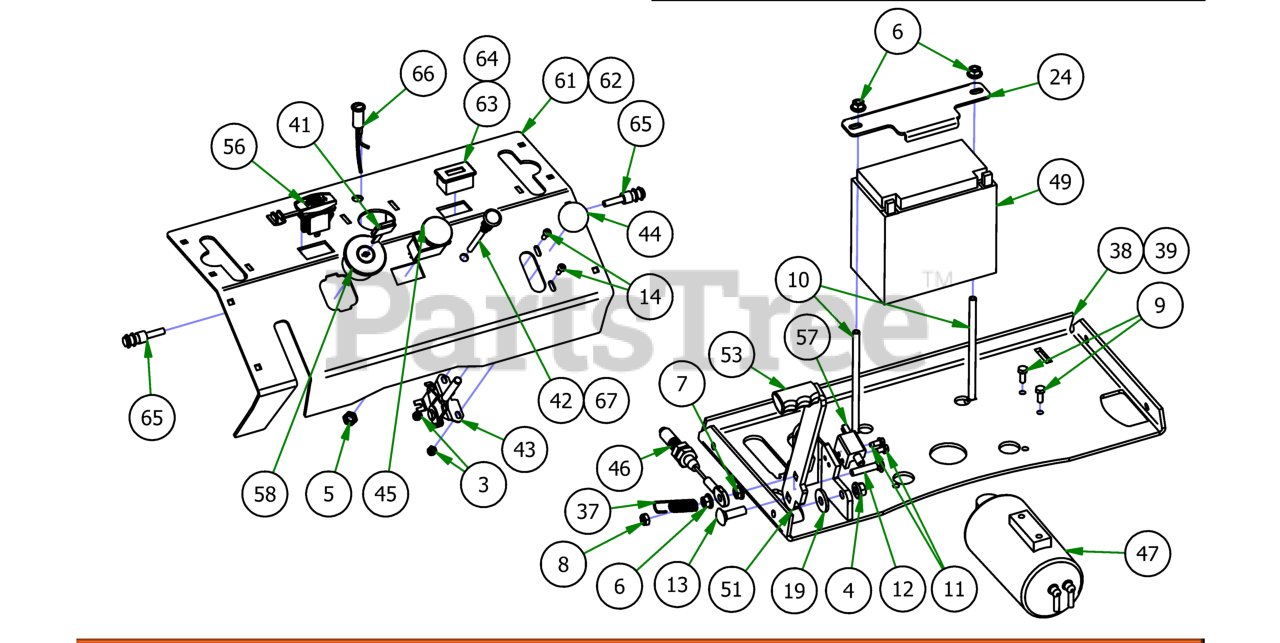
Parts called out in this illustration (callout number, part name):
1	8-32 HEX M/S NUT ZINC
2	1/4-20 NYL INSERT FLANGE LOCKNUT ZINC
3	10-24 NYLON INSERT LOCKNUT ZINC
4	3/8-16 NYLON INSERT FLANGE LOCKNUT (GR.F) ZINC
5	3/8-24 HEX NUT ZINC YELLOW
6	5/16-18 NYLON INSERT FLANGE LOCKNUT ZINC
7	5/16-18 HEX SERRATED FLANGE NUT HARD/ZINC
8	5/16-18 Nylock Jam Nut 1/2 Nut
9	M6-1.0 X 16MM Hex Bolt
10	5/16-18 X 6 CARRIAGE BOLT (GR.5) ZINC
11	12-24 X 1/2 HEX WASHER UNLSOT F TCS ZINC
12	5/16-18 X 1-1/2 CARRIAGE BOLT ZINC
13	3/8-16 X 1-1/4 CARRIAGE BOLT ZINC
14	10-24 X 5/8 BUTTON SOCKET CAP SCREW 18-8 STAINLESS STEEL
15	3/8-16 X 1 GR 5 Hex Bolts Zinc
16	1/4-20 X 3/4 CARRIAGE BOLT ZINC
17	5/16-18 X 1 CARRIAGE BOLT (GR.8) ZINC
18	.390 ID X .750 OD X .062 THK FLAT WASHER NYLON
19	.390 ID X 1.12 OD X .125 THK FLAT WASHER NYLON
20	3/8 FLAT WASHER USS (1" OD) ZINC
21	3/8 SPLIT LOCKWASHER ZINC
22	1/4-20 X 3/4 CARRIAGE BOLT (GR.5) ZINC
23	1/4" Press in Grease Fitting
24	2019 Stand On Battery Hold Down
25	2020 36" Hydrotank Carrier Plate
26	2019 Stand On Control Arm Stop Weldment
27	2019 Stand On Control Arm Stop Weldment_rear
28	2019 Stand On Drive Arm Actuator weldment_right
29	2019 Stand On Drive Arm Actuator weldment_left
30	2019 Drive Arm Bushing
31	36" Revolt Rear Control Arm Stop Weldment
32	36" Front Control Arm Stop Weldment
33	36" RH Drive Arm Actuator Weldment
34	36" Revolt LH Drive Arm Actuator Weldment
35	2019 Stand On Drive Arm Pivot Bar
36	2020 36" Stand On Drive Pivot Bar
37	Brake Spring
38	2019 Stand On Console Bracket Weldment
39	36" Console Bracket Weldment
40	Ratchet Fastener (36" ONLY)
41	Ignition Key
43	Universal Throttle
44	Throttle Knob
45	PTO Switch
46	Brake Cable
47	Revolt EPA Cannister Assy
48	Hydro Tank Assembly
49	Interstate FAYTX14 Battery
50	8507A13 McMaster Carr Plunger
51	2019 Stand On Brake Handle
52	2019 Stand On Control Grip
53	Rubber Brake Grip-cZT/ZT 2013
54	2019 Stand On Waterbottle Cage
55	Magnet-Steering Arm-Stand ON
57	Safety Switch
58	Ignition Switch
59	2019 Podium Panel Right
60	2019 Podium Panel Left
61	2019 Stand On Podium Front Panel Weldment
62	36" Podium Front Panel Weldment
63	Tachometer
64	Tachometer-Kohler/Yamaha EFI
65	Safety Switch Harness
67	Code Indicator Light-Yamaha
